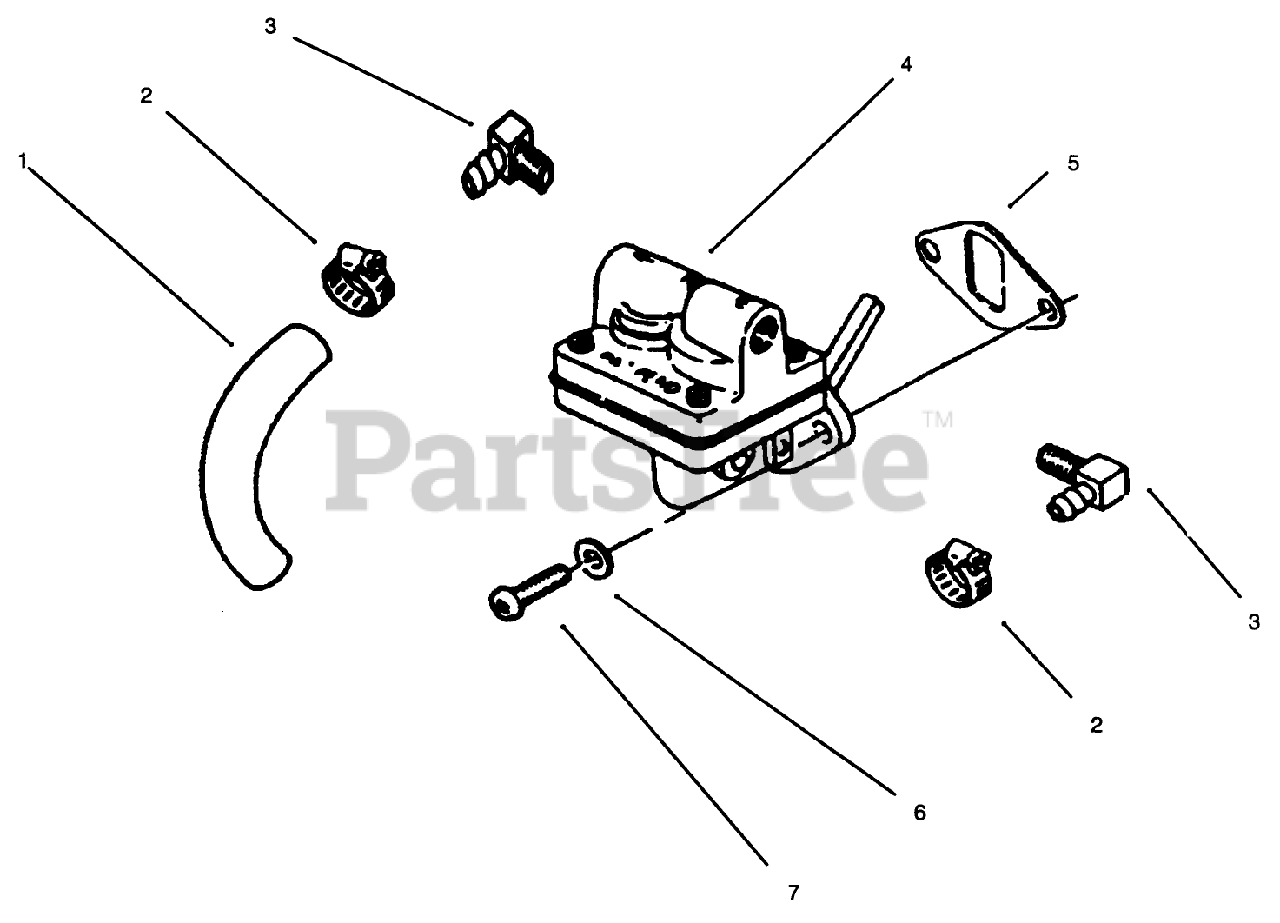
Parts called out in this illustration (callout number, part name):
1	Line-Fuel
2	Clamp
3	Connector-90?
4	Pump ASM-Fuel INC 57
5	Gasket
6	Washer
7	Screw-F.H.
